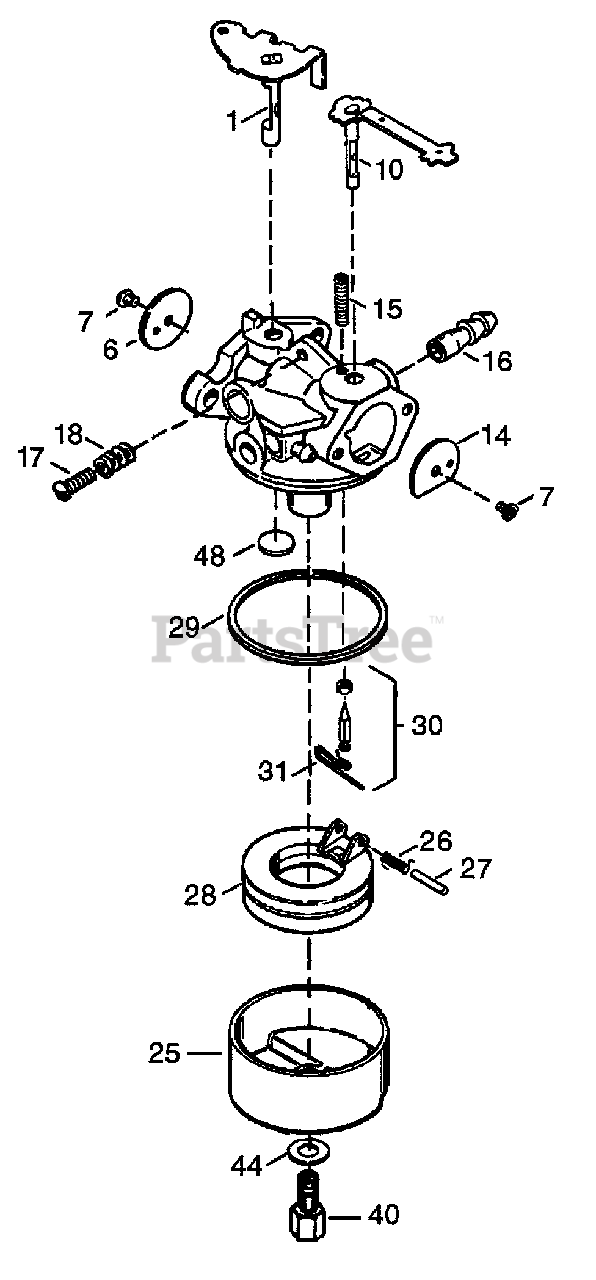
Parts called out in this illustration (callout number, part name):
1	Throttle Shaft & Lever Assy
6	Throttle Shutter
7	Shutter Screw
10	Choke Shaft & Lever Assy
14	Choke Shutter
15	Choke Positioning Spring
16	Fuel Fitting
25	Float Bowl
26	Float Dampening Spring
27	Float Shaft
28	Float
29	Float Bow "O" Ring
30	Inlet Needle, Seat & Clip
31	Spring Clip
40	High Speed Bowl Nut
44	Bowl Nut Washer
48	Welch Plug, Atmospheric Vent
